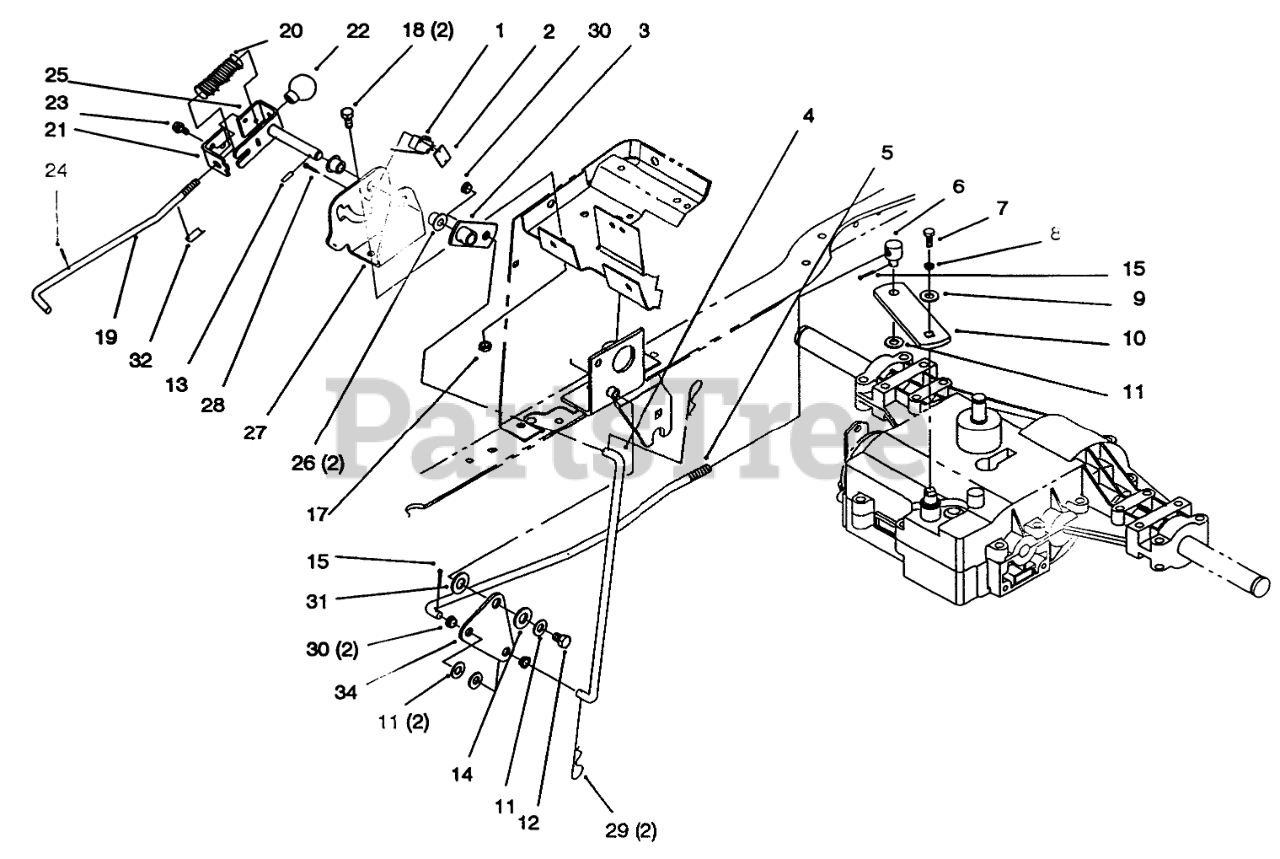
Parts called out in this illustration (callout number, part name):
1	Switch-Clutch (Only On: 72042, 72062)
2	Nut-Speed (Only On: 72042,72062)
3	Tube-Linkage (Only On: 72042, 72062)
4	Rod (Only On: 72042, 72062)
5	Rod-Shift Transaxle (Only On: 72042, 72062)
6	Trunnion (Only On: 72042, 72062)
7	Screw (Only On: 72042, 72062)
8	Washer-Lock (Only On: 72042, 72062)
9	Spacer-Transmission (Only On: 72042, 72062)
10	Arm-Shift (Only On: 72042, 72062)
11	Washer-Flat (Only On: 72042, 72062)
12	Screw-HH (Only On: 72042, 72062)
13	Pin-Roll (Only On: 72042, 72062)
14	Washer-Belleville (Only On: 72042, 72062)
15	Pin-Cotter (Only On: 72042, 72062)
17	Nut-Hex Lock (Only On: 72042, 72062)
18	Screw-HH (Only On: 72042, 72062)
19	Rod-Shift (Only On: 72042, 72062)
20	Spring-Compression (Only On: 72042, 72062)
21	Bracket-Shaft (Only On: 72042, 72062)
22	Knob (Only On: 72042, 72062)
23	Screw-TAP (Only On: 72042, 72062)
24	Pin-Roll (Only On: 72042, 72062)
25	Pivot-Shift (Only On: 72042, 72062)
26	Bushing (Only On: 72042, 72062)
27	Bracket-Pivot Mount (Only On: 72042, 72062)
28	Screw (Only On: 72042, 72062)
29	Pin-Cotter (Only On: 72042, 72032)
30	Bearing-Shift Link (Only On: 72042, 72062)
31	Washer-Thrust (Only On: 72042, 72062)
32	Decal-Reverse Shift (Only On: 72042)
32	Decal-Reverse Shift (Only On: 72062)
34	Bracket-Pivot (Only On: 72042, 72062)
